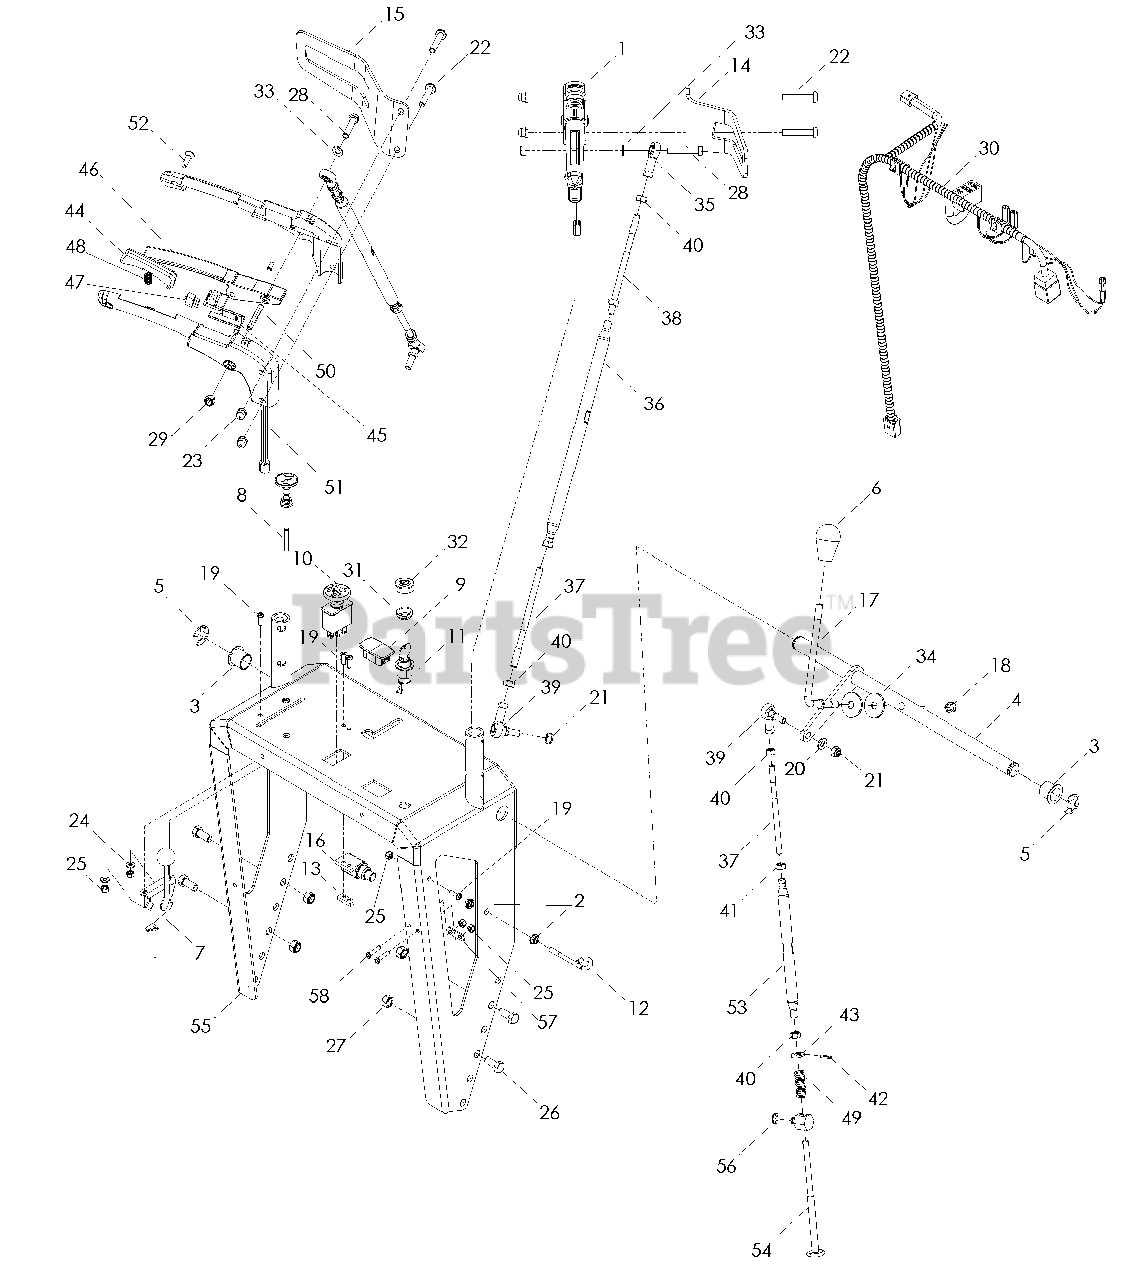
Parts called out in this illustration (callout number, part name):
1	GRIP ASSEM
2	NUT 5/16-18 HEX WHIZLK
3	BEARING, FLANGE
4	SPEED CONTROL
5	E RING, 20MM
6	KNOB, SHIFT
7	THROTTLE CONTROL
8	CONTROL, CHOKE
9	PLUG, DASH, SVC MINDER
10	CLUTCH SWITCH
11	SWITCH, IGNITION
12	GUIDE, ROPE
13	PLATE, NUT
14	GUARD, HAND RH
15	GUARD, HAND LH
16	SWITCH, NC
17	ROD, SHIFT
18	NUT 3/8-16 HEX JAM NYLOC
19	SCREW #10-24 x 1/2 HEX
20	WASHER 5/16 SAE FLAT
21	NUT M8 x 1.25 NYLOC
22	SCREW, PAN HD 5/16-18 x 1 3/4
23	NUT, ACORN 5/16-18
24	WASHER #10 FLAT
25	NUT #10-24 HEX NYLOC
26	HCS 3/8-16 x 7/8
27	NUT 3/8-16 HEX NYLOC
28	HCS 5/16-18 x 1 3/4
29	NUT 5/16-18 HEX NYLOC
30	HARNESS, UPPER HANDLE
31	NUT, IGNITION SWITCH
32	CAP, IGNITION SWITCH NUT
33	WASHER 5/16 SLW
34	WASHER, CONE
35	ROD END 8 MM, RH
36	TUBE, ADJUSTING
39	ROD END 8 MM, W/STUD
40	NUT .8MM x 1.25 HEX
41	NUT .8MM x 1.25 LH
42	ROLL PIN 3 MM
43	WASHER, 10 MM
44	ACTUATOR, OPC
45	LOCK, NEUTRAL
50	PIN, GROOVE 1/4 x 1 1/2
51	HARNESS, SWITCH
52	SCREW, OVAL HEAD 6MM
53	TUBE, ADJUSTING
54	ROD, HEADED
55	UPPER HANDLE W/DECAL
56	E-RING, 10MM
57	PLATE, RESISTOR
58	SCREW #10-24 x 7/8 RD HD
